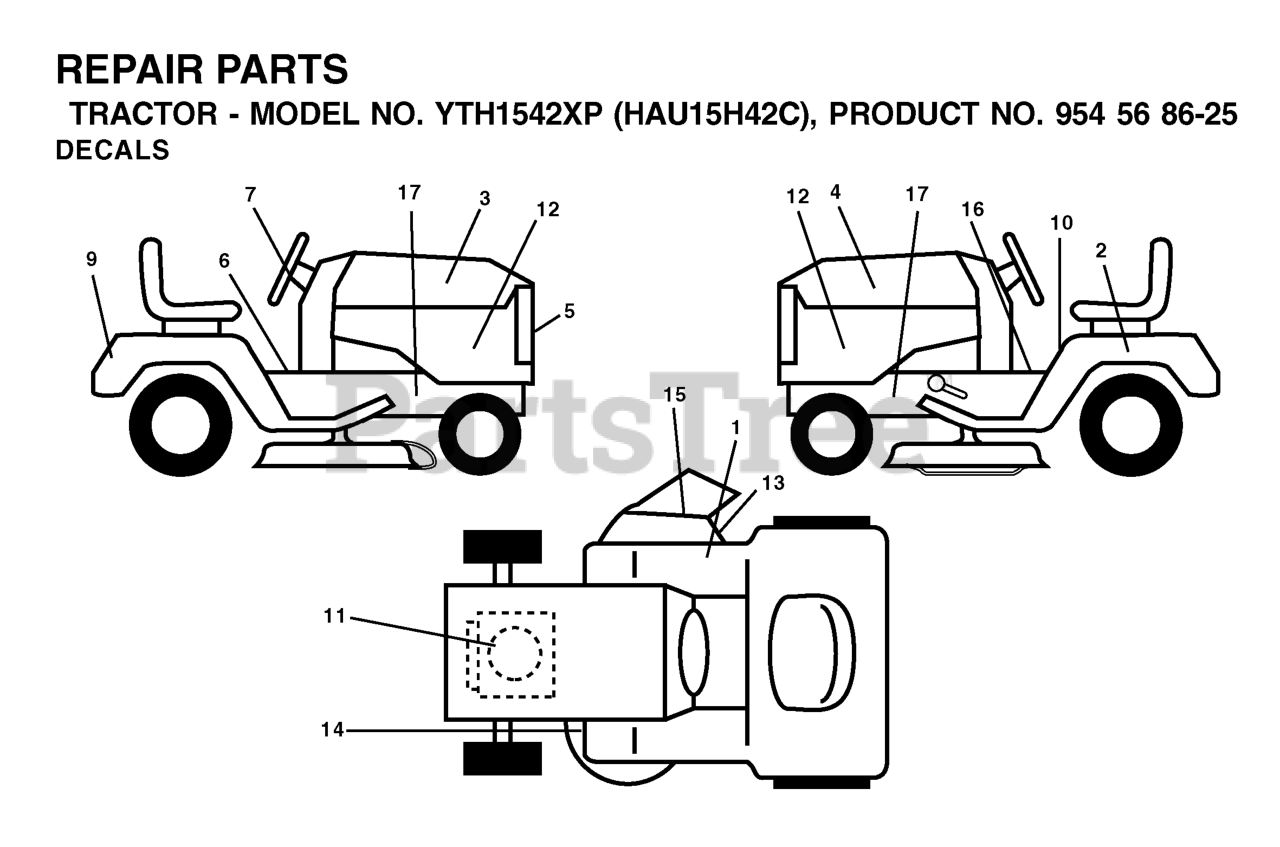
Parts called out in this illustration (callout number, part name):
1	DECAL
2	DECAL BTRY SYMBOLS
3	DECAL HOOD RH
4	DECAL HOOD(L)YTH1542XP
5	DECAL.GRILLE.HUSQ
6	DECAL PARK BRAKE
7	DECAL.WHEEL.STEERING.HUSQ.PERM
9	DECAL, FENDER
10	DECAL READ OWNER'S MAN SYMS
12	DECAL HOOD
13	DECAL.INTERNATIONL.CUTFINGER
14	DECAL V BELT SCHEMATIC
15	DECAL DECK "B" 42"
16	DECAL
